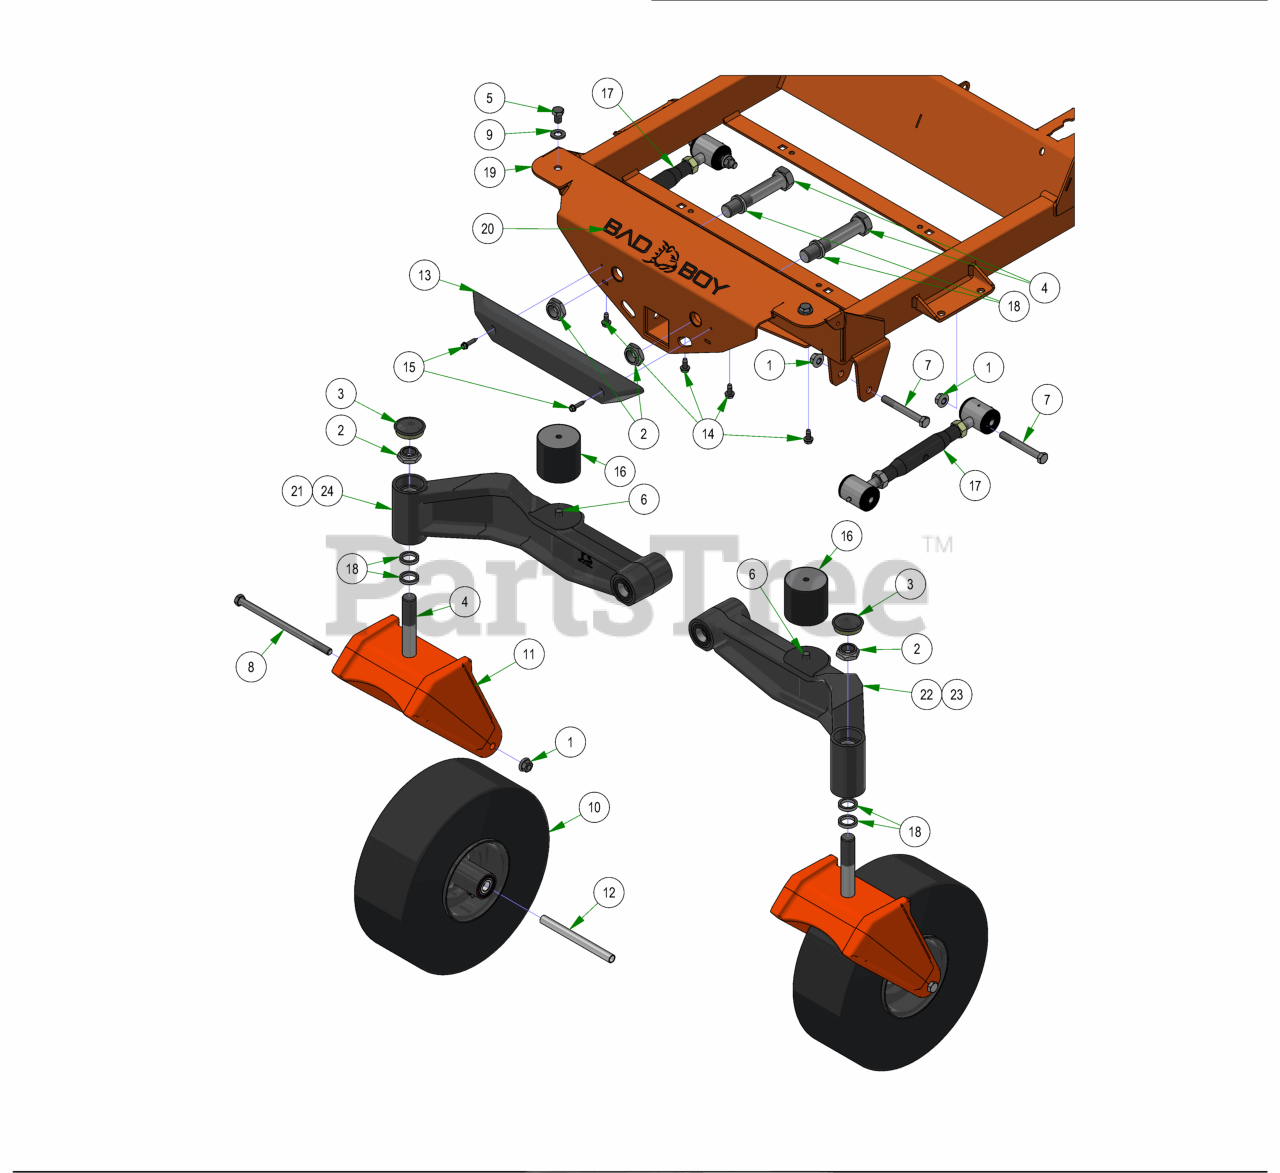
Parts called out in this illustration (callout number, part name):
1	1/2-13 NYLON INSERT FLANGE LOCKNUT ZINC
2	1"-14 NYLON INSERT JAM LOCKNUT ZINC
3	2017 Bearing Cover
4	1"-14 X 5-1/2 HEX CAP SCREW (GR.8) ZINC YELLOW
5	1/2-13 X 3/4 HEX CAP SCREW (GR.5) ZINC
6	1/2-13 x 1" Stud
7	1/2-13 X 4 HEX CAP SCREW (GR.8) ZINC YELLOW
8	1/2-13 X 9 HEX CAP SCREW (GR.5) ZINC
9	1/2 SAE FLAT WASHER (1-1/16" OD) GR.8 ZINC YELLOW
10	2019 15x6.00-6 Non Pneumatic Black Front Assembly
11	2020 R Series Cast Front Fork
12	Front Wheel Spanner
13	2017 XP Bumper
14	5/16-18 X 3/4HEX WASHER SLOT (F) TCS ZINC
15	1/4-14 X 1-1/4 HEX WASHER UNSLOT TEK/3 ZINC
16	Vibration Mount-Blue Dot
17	Turnbuckle Assembly (M20-2.5)
18	1.02 ID X 1.38 OD X .250 THK SPACER ZINC
19	2023 Rogue Frame - Painted
20	Flying Bulldog Front Bumper Decal
21	2022 61/72 Rogue/Renegade Front Suspension Asy RH
22	54 ROGUE FRONT SUSPENSION ASSEMBLY LH
23	2022 61/72 Rogue/Renegade Front Suspension Asy LH
24	54 ROGUE FRONT SUSPENSION ASSEMBLY RH
